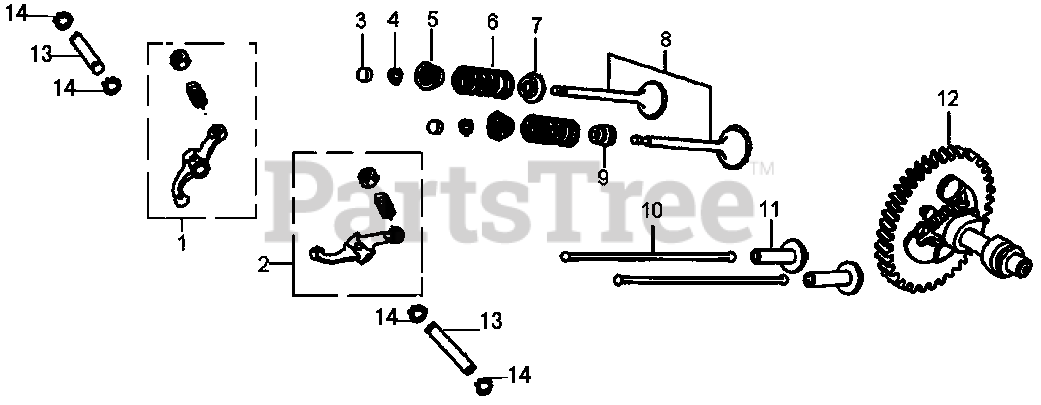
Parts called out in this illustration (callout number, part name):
1	ROCKER ARM ASSY.
2	ROCKER ARM ASSY.
3	ROTATOR,VALVE
4	VALVE LOCKER
5	RETAINER,VALVE SPRING
6	SPRING,VALVE
7	SEAT,VALVE SPRING
8	VALVE ASSY.
9	SEAL,VALVE STEM
11	LIFTER , VALVE
12	CAMSHAFT ASSY
13	ROCKER ARM SHAFT
